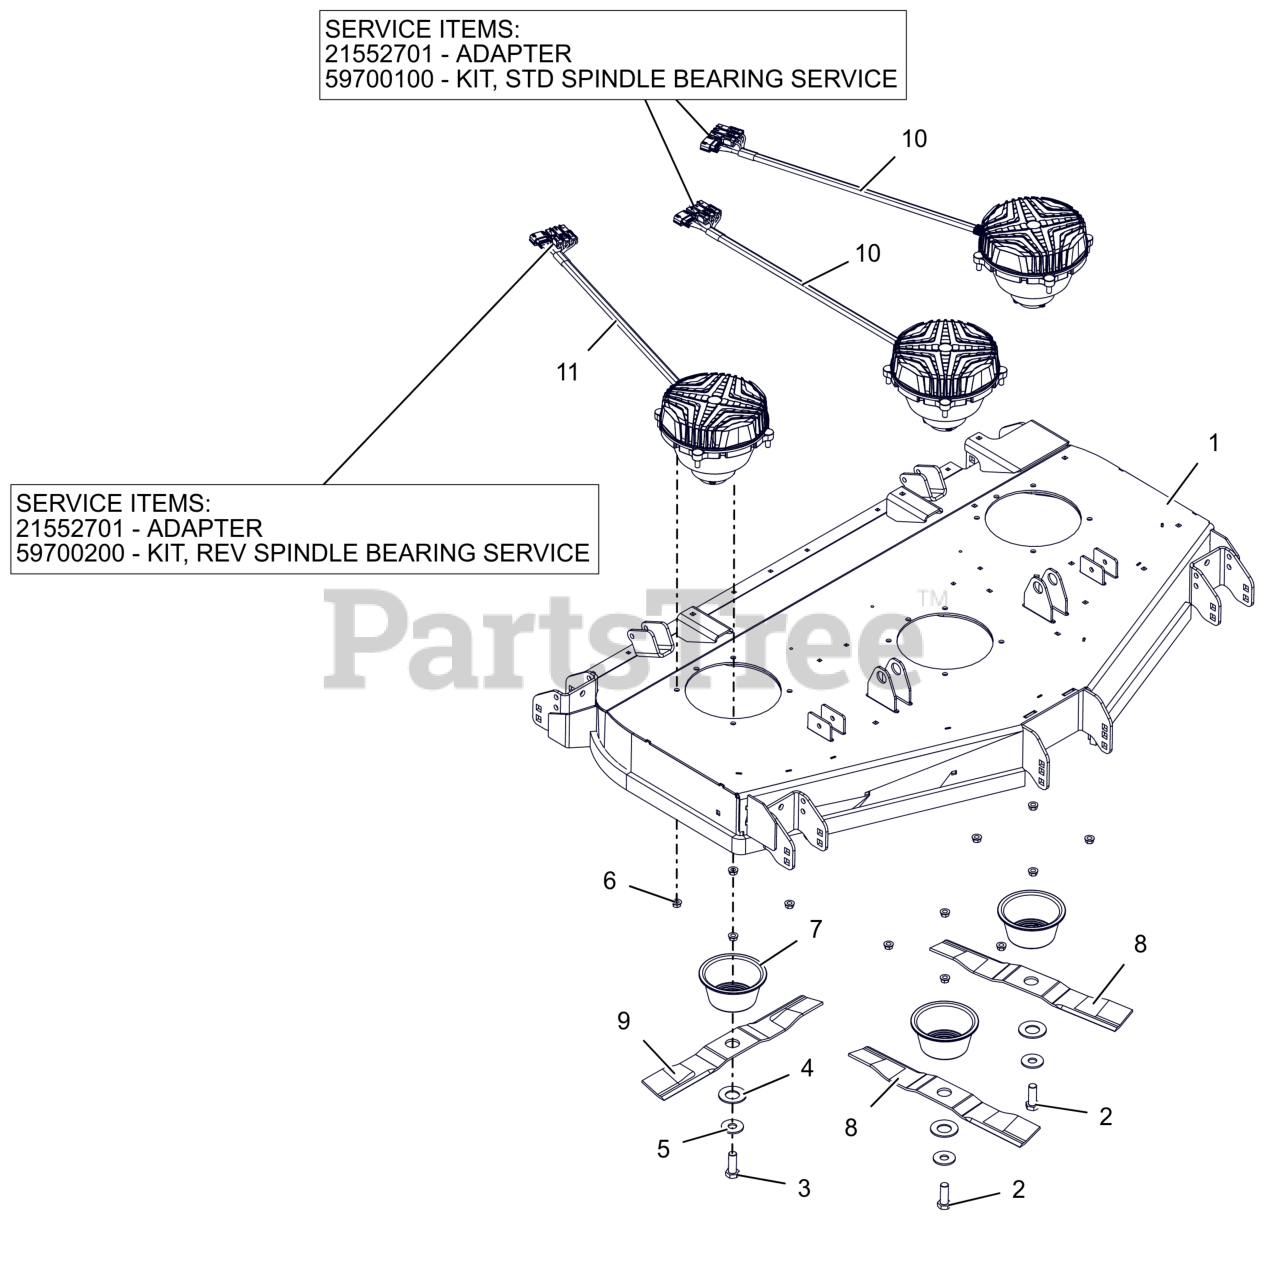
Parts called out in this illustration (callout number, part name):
1	WLDMT, 52" PSEV REAR DISCHARGE DECK (ORANGE)
2	BLT, HEX .62-18X1.75 G8 ZCC
3	BLT, HEX 0.625-11X1.75 GR8 ZCC LH
4	WSHR, BLVL - .56X28.5X3 PHOS.COAT
5	WSHR, HRDN 0.687X1.75X0.134 HRD
6	NUT-LK-CTR-FLG .375-16 GF ZCC
7	GUARD, SPINDLE LOWER
8	BLADE- MOWER-18.00" LOW
9	BLADE, MOWER -18.00" EFF CCW
10	MOTOR, DECK - 48"/52" CW
10	ADAPTER
10	KIT,STD SPINDLE BEARING SERVICE
11	MOTOR, DECK - 48"/52" CCW
11	ADAPTER
11	KIT,REV SPINDLE BEARING SERVICE
